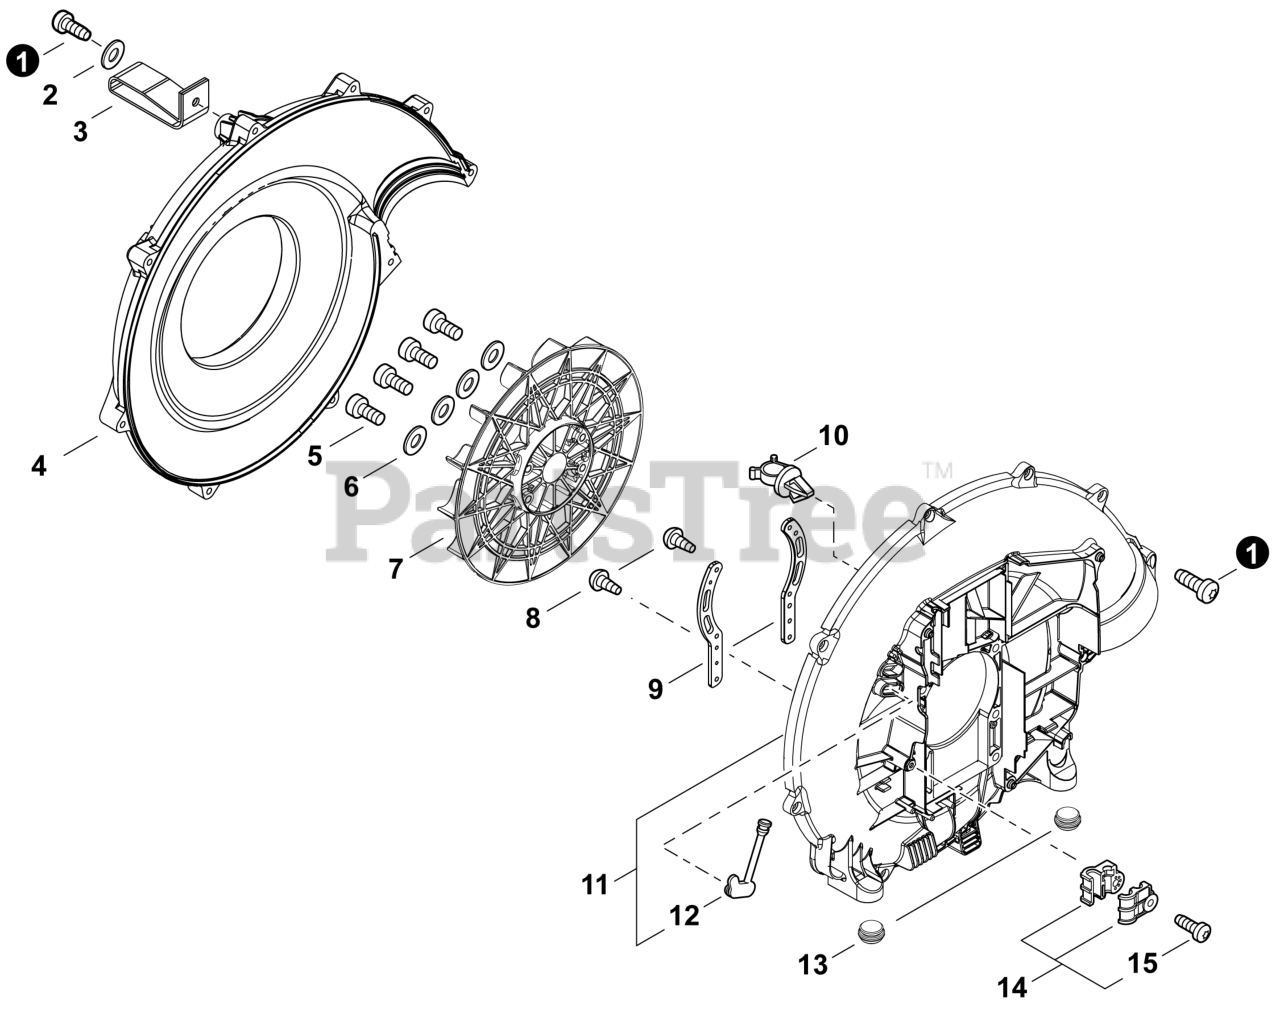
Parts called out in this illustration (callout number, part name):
1	BOLT, TORX 5x20
2	WASHER 5.5x16x2T
3	STRAP, SAFETY
4	FAN COVER, PB-580
5	BOLT, TORX 5x30
6	WASHER 5.5x16x2T
7	FAN, BLOWER
8	SCREW, TAPPING 3x12
9	BRACKET, ENGINE
10	CLIP, CABLE
11	CASE KIT, FAN
12	GROMMET
13	CUSHION
14	CABLE HOLDER SET
15	BOLT, TORX 5x25
